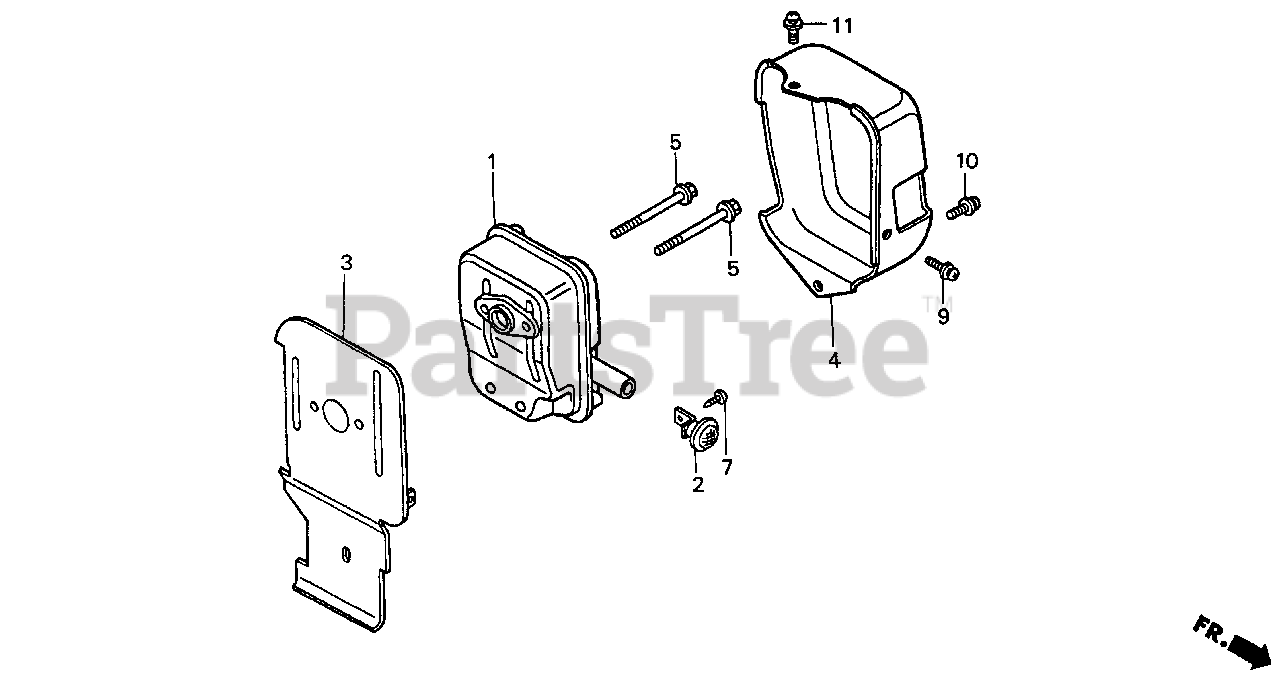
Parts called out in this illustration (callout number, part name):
1	MUFFLER COMP.
2	ARRESTER, SPARK
3	GUIDE, AIR EX.
4	INNER COVER, TOP
5	BOLT, FLANGE (5X50)
7	SCREW, TAPPING (4X6)
9	SCREW-WASHER (5X8)
10	SCREW-WASHER (5X10)
11	SCREW-WASHER (5X16)
